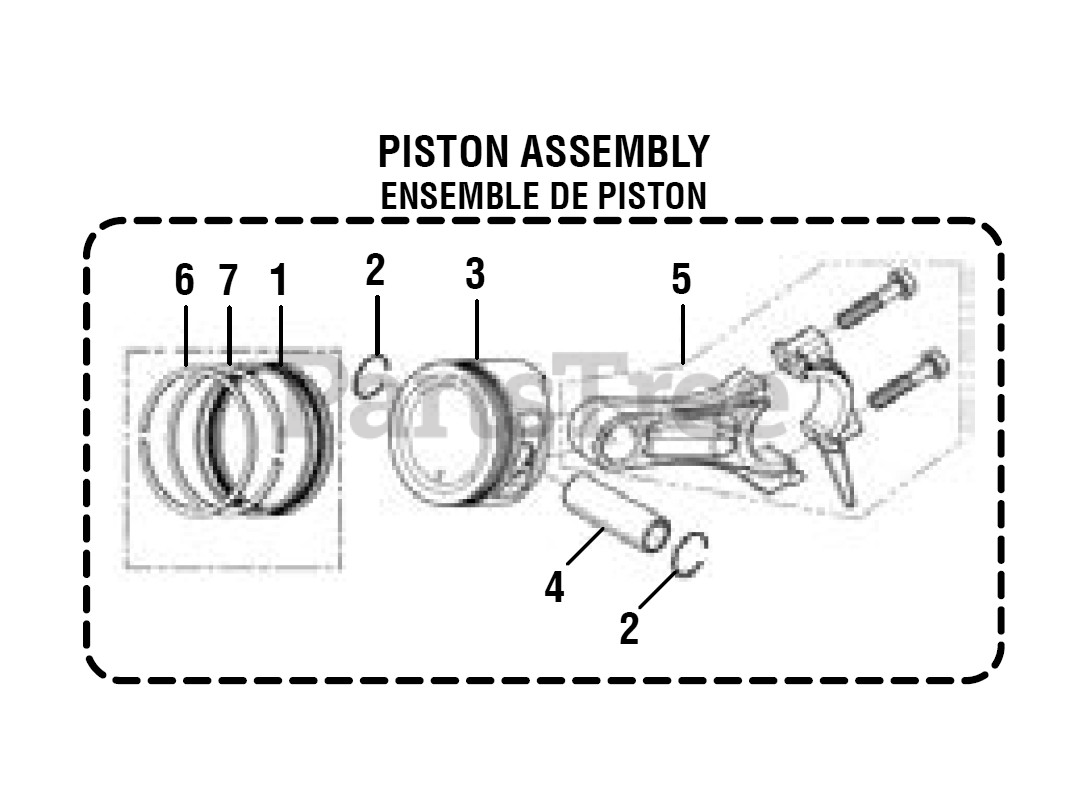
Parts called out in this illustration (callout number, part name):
1	Oil Ring Kit
2	Piston Pin Clip
3	Piston
4	Piston Pin
5	Connecting Rod
6	The First Ring
7	The Second Ring
